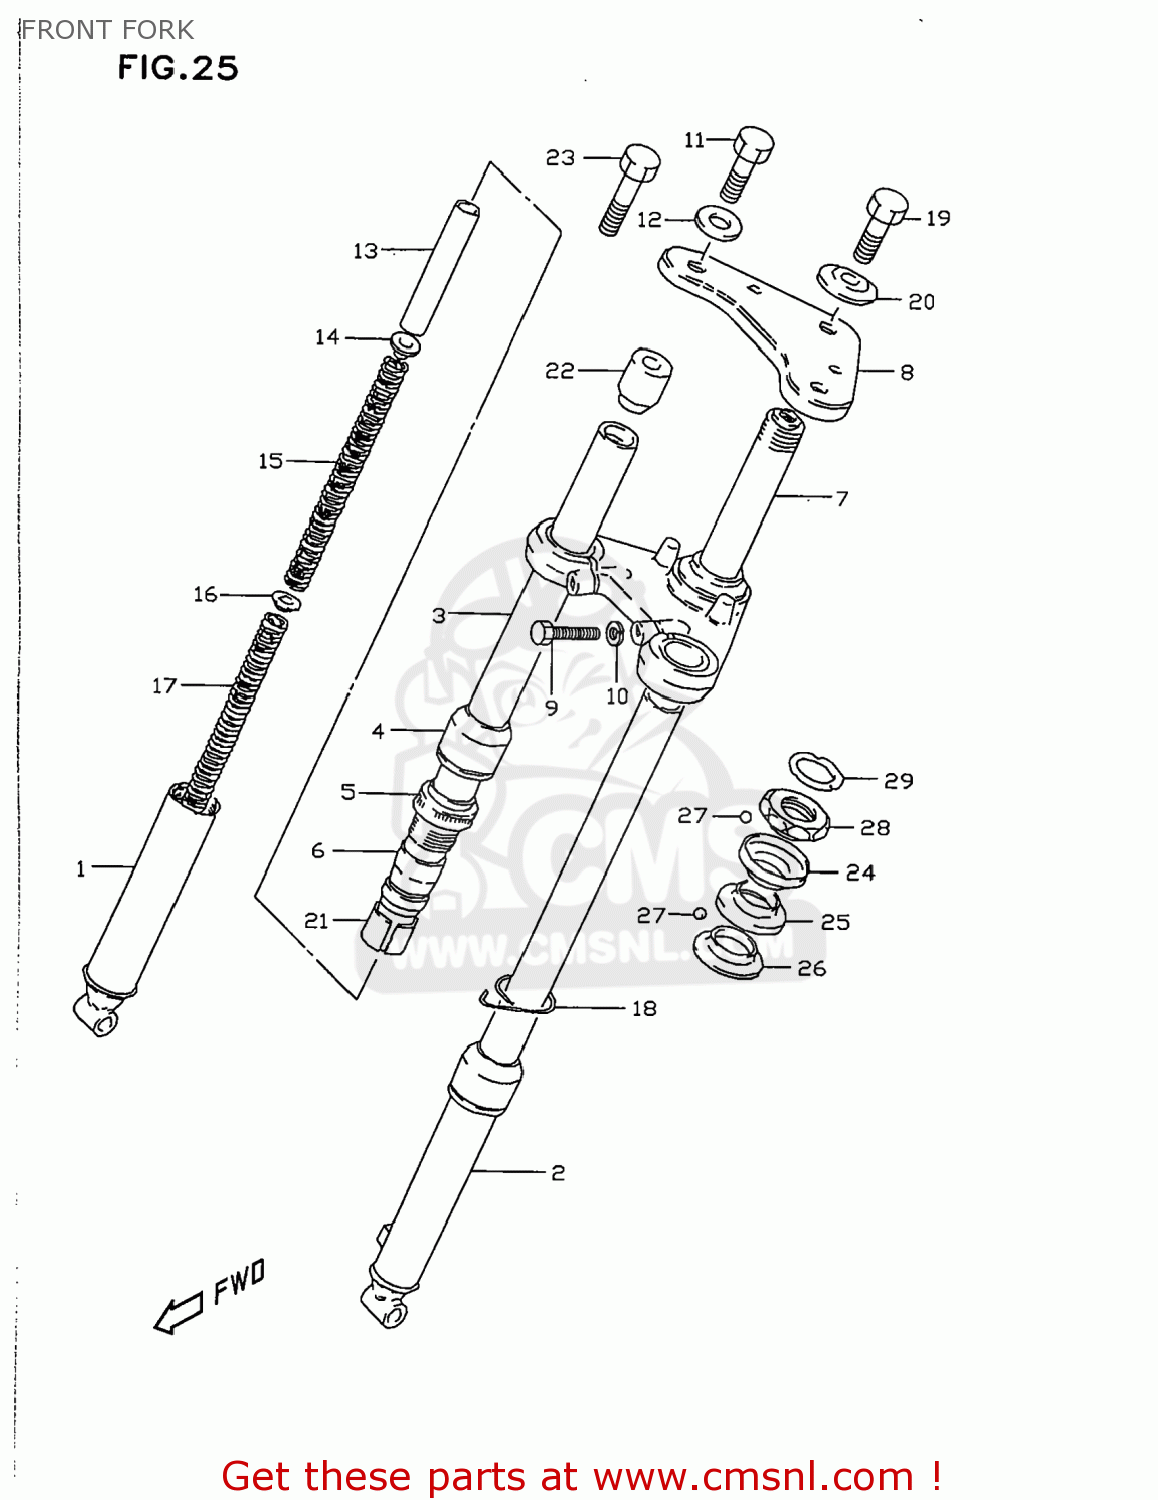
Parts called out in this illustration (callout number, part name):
1	TUBE,OUTER,R
2	TUBE,OUTER,L
3	TUBE,INNER
4	SEAL,DUST
5	NUT,OUTER
6	STOPPER
7	STEM,STEERING
8	HEAD,STEERING STEM
9	BOLT
10	WASHER,LOCK
11	BOLT
12	WASHER,STEERING STEM HEAD
13	SPACER
14	GUIDE,SPRING
15	SPRING,NO.1
16	GUIDE,SPRING NO.2
17	SPRING,NO.2
18	CLIP
19	BOLT
20	WASHER(33.5X10.5X4.2)
21	BUSH,SLIDE(33221-00801)
22	SPACER,FR FORK INNER TUBE
23	BOLT,FRONT FORK INNER TUBE
24	RACE,STEERING,INNER,UPPER
25	RACE,STEERING,INNER,LOWER
26	RACE,STEERING,OUTER,LOWER
27	BALL
28	RACE,STEERING,OUTER,UPPER
29	NUT
